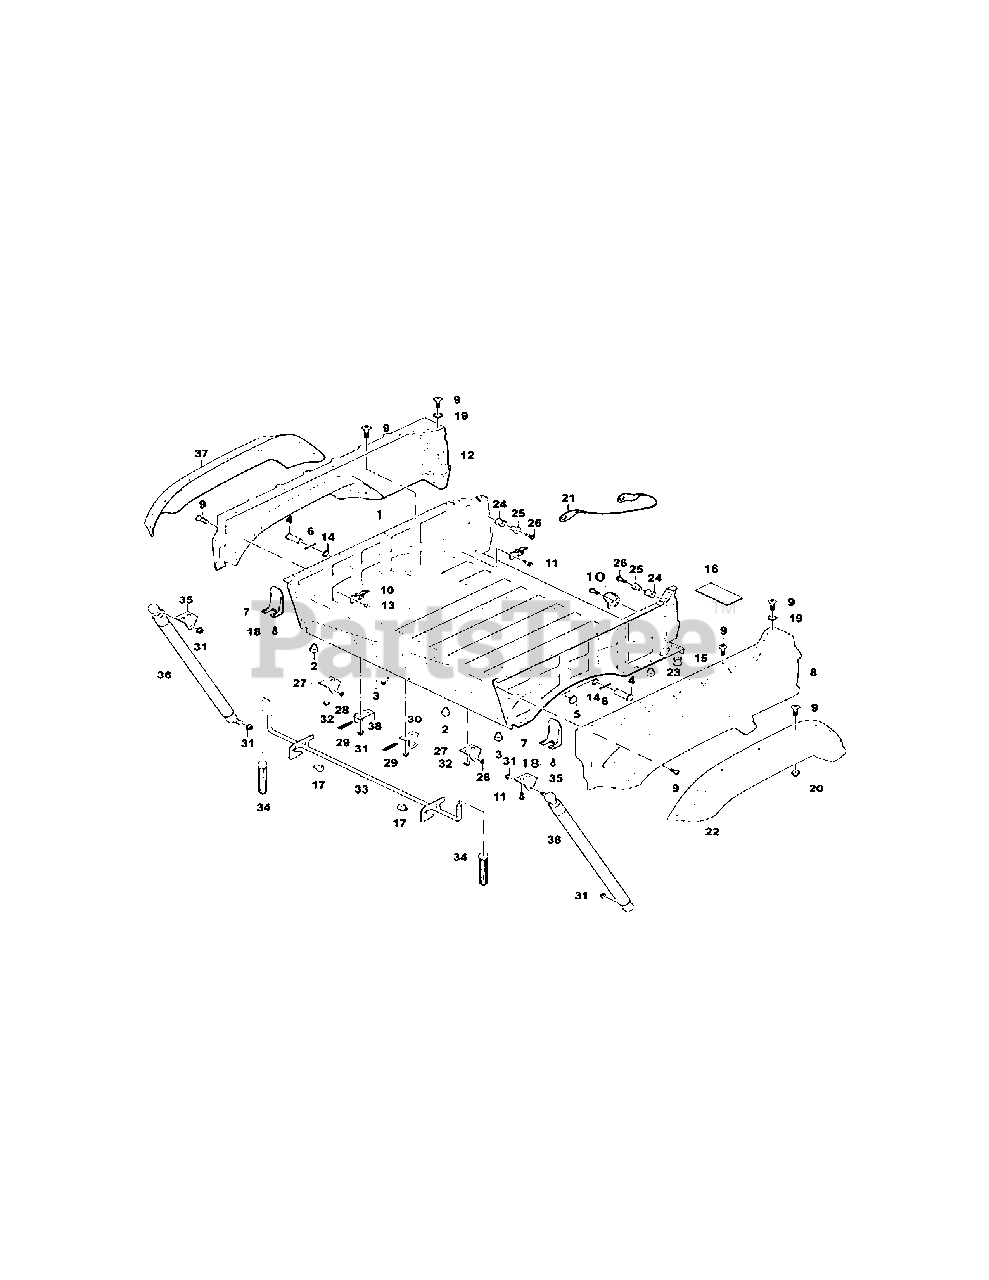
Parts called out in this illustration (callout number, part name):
1	Rear Carrier Assy
2	Shock Absorber Cushion IV
3	Shock Absorber Cushion I
4	Pin 12×62
5	Rubber Cushion III
7	Invert Bracket Board, Carrier
8	Left Side Board Assy, Carrier Yellow
8	Left Side Board Assy, Carrier Camo
9	Cross large plate head screw M6×16
10	Drawstring Pothook
11	Hexagon Flange Bolt M6×12
12	Right Side Board Assy, Carrier Yellow
12	Right Side Board Assy, Carrier Camo
13	Cap Nut M6×17
14	Wahser13×24×1.5
15	I-Shaped Rubber Ring IV
16	Rubber Cushion,Carrier
17	Nylon Bushing IV
19	Washer6×18×1.6
20	Hexagon Flange Self-Lock Nuts M6
21	Trunk Cable
22	Cargo Bed Left Decoration Plate
23	Shock Absorber Cushion III
24	I-Shaped Rubber Ring
25	Bushing 6.5×9×22×17
26	Hexagon flange bolt M6×40
27	Left Invert Bracket Support Lug
28	I-Shaped Rubber Ring IV
29	Tension Spring III
30	Left Mounting Board, Invert Bracket
31	Hexagon Flange Lock Nut M8 (Metallic Insert)
32	Hexagon Flange Nut M6
33	Invert Bracket Assy, Carrier
34	Handle Sheath II
35	Gas Spring Mounting Plate
36	Gas Spring Assy
37	Cargo Bed Right Decoration Plate
38	Right Mounting Plate, Invert Bracket Assy
